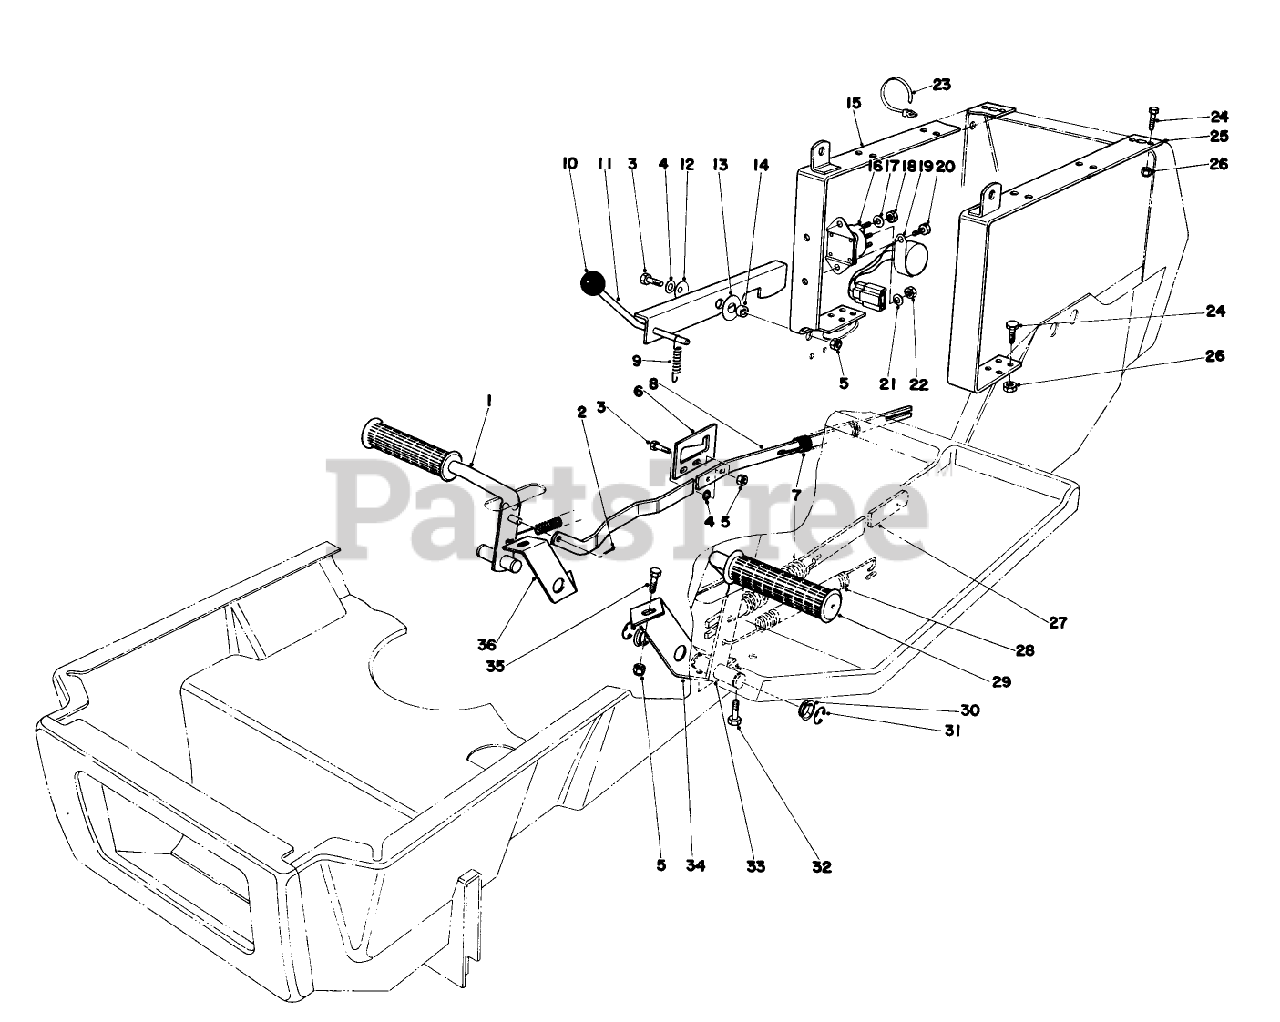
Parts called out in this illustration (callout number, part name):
2	PIN-COTTER
3	SCREW-HH
4	WASHER-PLAIN
5	NUT-LOCK, CONE
12	Belleville Washer
13	WASHER-PLASTIC
16	SOLENOID
17	WASHER-LOCK
18	NUT-JAM, BRASS
20	SCREW-HWH
21	WASHER-LOCK
22	NUT-HEX
23	TIE-MOUNT, PUSH
24	SCREW-HH
26	NUT-LOCK, CONE
28	SPRING-EXTENSION
31	E-RING
32	SCREW-THD ROLL, HWH
33	CLUTCH PEDAL WA *BO
35	SCREW-HH
